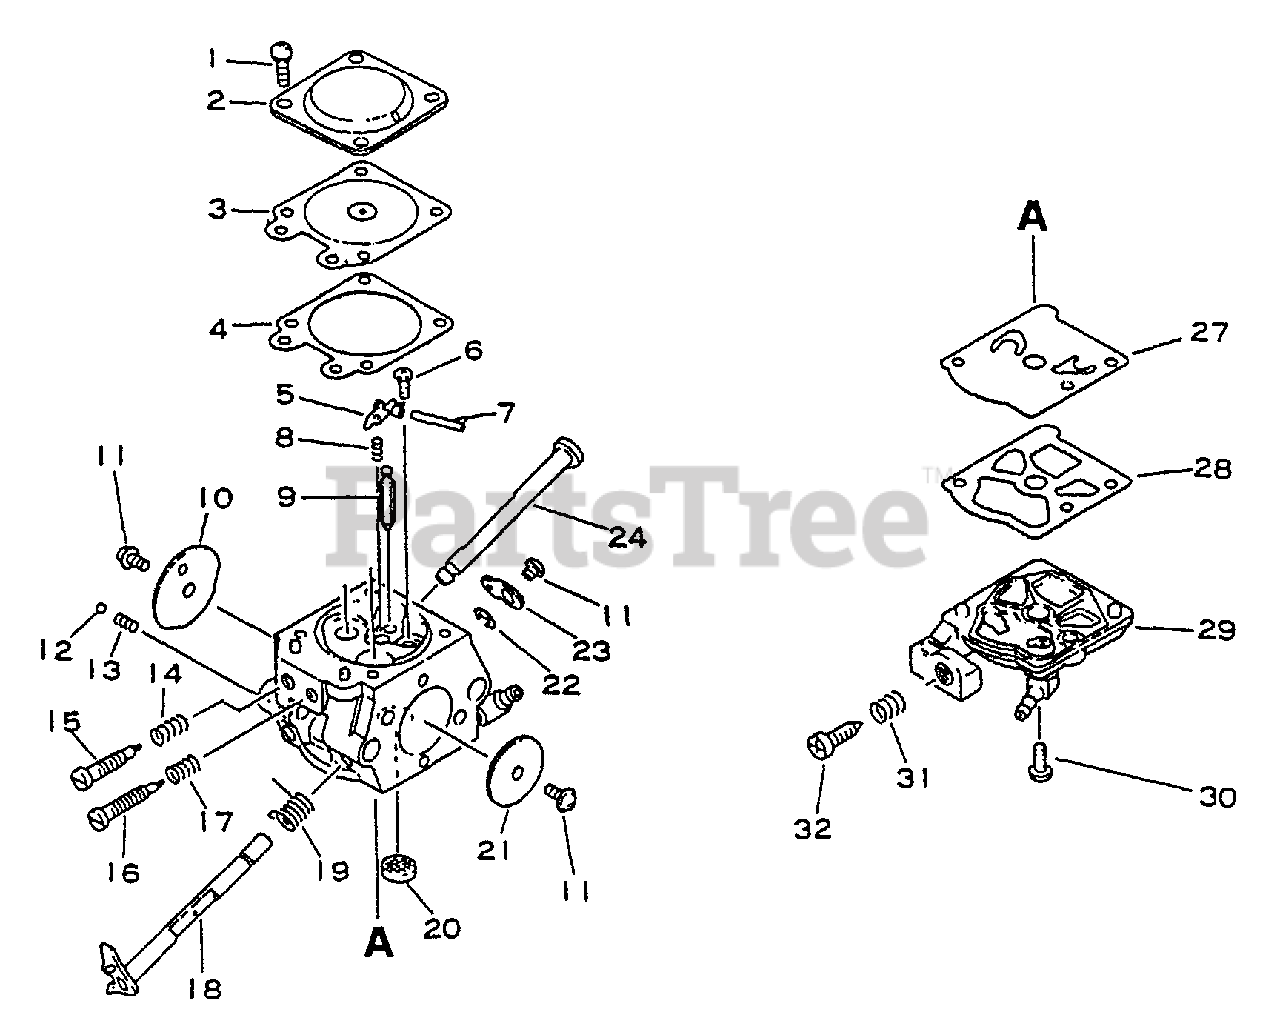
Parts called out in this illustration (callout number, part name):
1	SCREW
2	COVER, METERING
3	DIAPHRAGM, METERING
4	GASKET, METERING
5	LEVER, METERING
6	SCREW, METERING LEVER PIN
7	PIN, METERING LEVER
8	SPRING, METERING LEVER
9	VALVE, INLET NEEDLE
10	VALVE, THROTTLE
12	BALL, CHOKE
14	SPRING
15	NEEDLE - HIGH SPEED
16	NEEDLE - LOW SPEED
18	SHAFT, THROTTLE
19	SPRING, THROTTLE RETURN
20	STRAINER
21	VALVE, CHOKE
22	CLIP, THROTTLE SHAFT
23	LEVER, THROTTLE
24	SHAFT, CHOKE
27	DIAPHRAGM, PUMP
28	GASKET, PUMP
29	COVER, PUMP
30	SCREW, PUMP COVER
31	SPRING, IDLE ADJUST
32	SCREW, IDLE ADJUST
